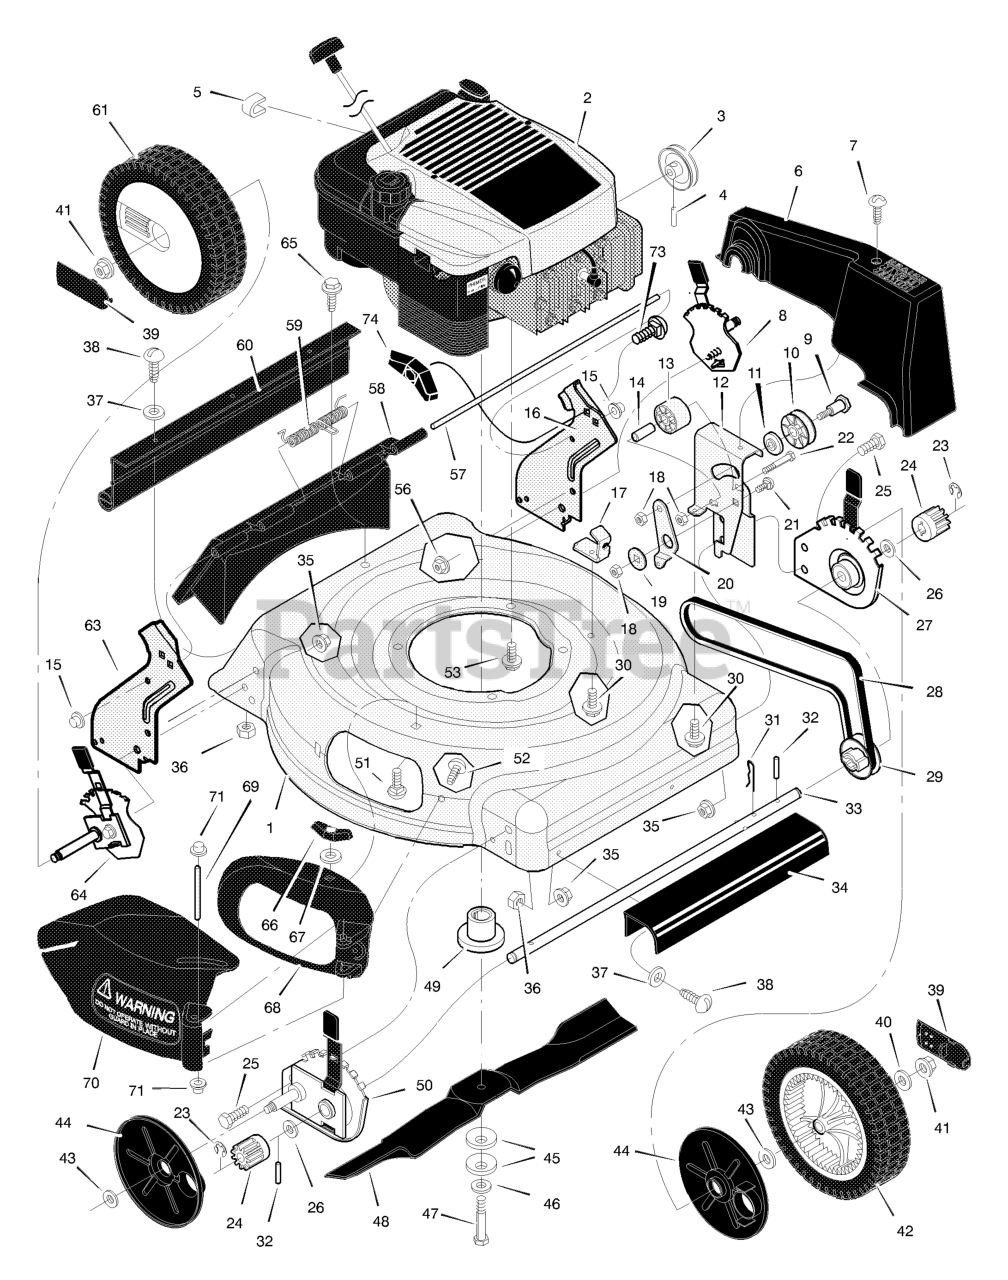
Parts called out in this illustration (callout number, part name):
1	Housing
2	Engine
3	Pulley, Engine
4	Pin, Spring
6	Cover, Belt (Black)
8	Adjuster, Left Rear Height
9	Bolt, Shoulder
12	Bracket, Idler Support
13	Pulley, Idler -Rear
14	Bearing
15	Nut, Push
16	Bracket, Left Handle
17	Bracket, Cable
18	Nut, Hex
20	Arm, Idler
21	Bolt, Carriage
22	Bolt, Shoulder
24	Gear, Pinion
25	Bolt
27	Adjuster, L. Frt. Height
29	Pulley, Axle
31	Pin, Hair
32	Pin, Spring
34	Cover, Axle (Black)
35	Nut, Flange
36	Nut, Hex
39	Cap, Hub
40	Washer
41	Nut, Flange
42	Wheel, Drive
44	Cover, Dust
45	Washer, Belleville
49	Adapter, Blade
50	Adjuster, R. Frt. Height
51	Bolt, Carriage
53	Bolt, Engine
55	Washer
56	Nut, Flange
57	Rod, Pivot
58	Door, Rear (Black)
59	Spring
60	Deflector, Rear
61	Wheel, Rear
63	Bracket, Right Handle
64	Adjuster, R. Rear Hgt.
66	Wingnut
67	Retainer, Push
68	Bezel (Black)
69	Pin, Pivot
70	Deflector, Chute (Black)
71	Push On Cap
73	Bolt, Carriage
